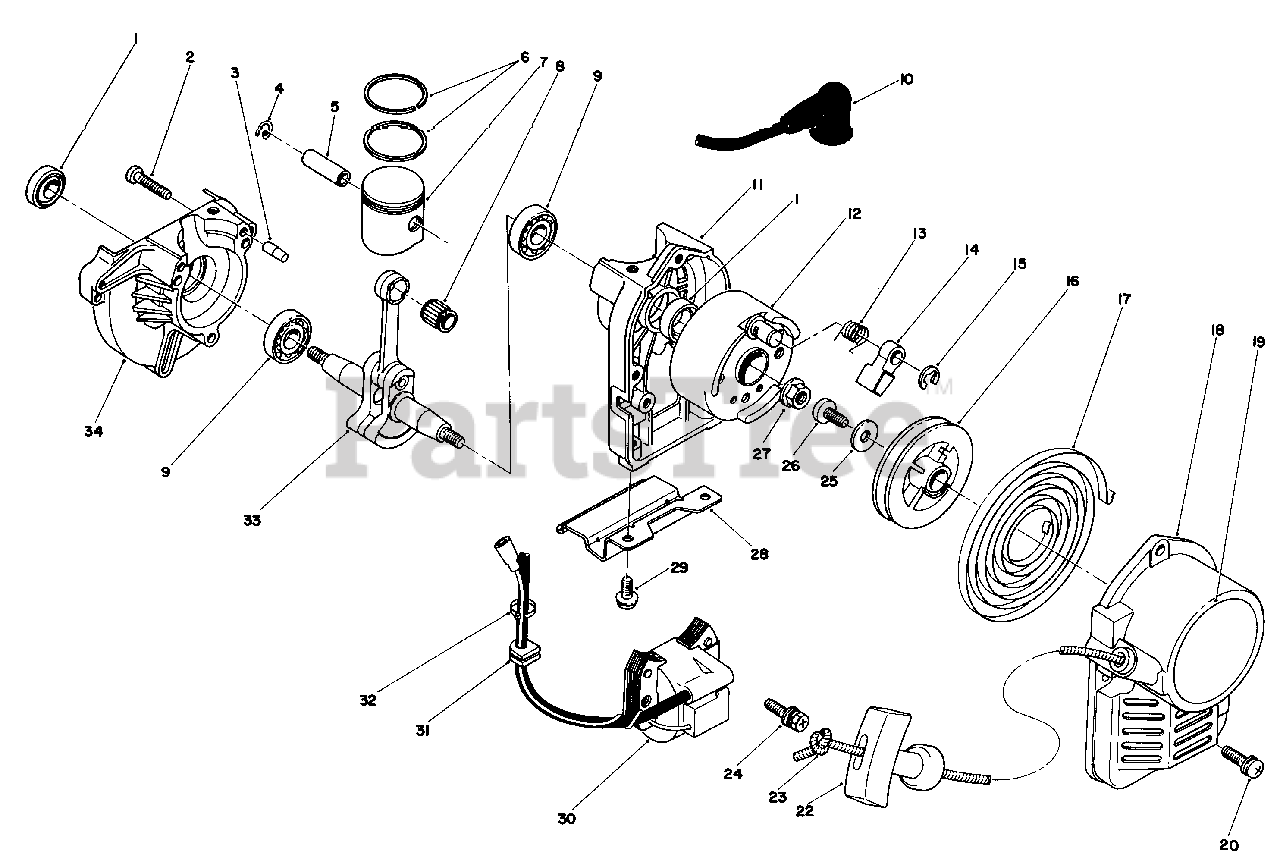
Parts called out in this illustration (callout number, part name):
1	Oil Seal
3	Pin, Dowel
4	Clip, Piston Pin
5	Pin, Piston
6	Ring, Piston
7	Piston Assembly (Incl. Ref. #5)
8	Bearing, Needle
9	Bearing, Ball
10	Cap, Plug
11	Case, Starter Side
13	Spring, Return
15	Snap Ring
17	Spring, Spiral
18	Case, Starter
19	Decal-Toro
20	Screw & Washer
22	Knob-Starter
23	Rope, Starter
24	Bolt & Washer
27	Nut, Conical Spring
29	Screw & Washer
30	Coil, Ignition
33	Crankshaft Assembly
34	Case, Drive Side
